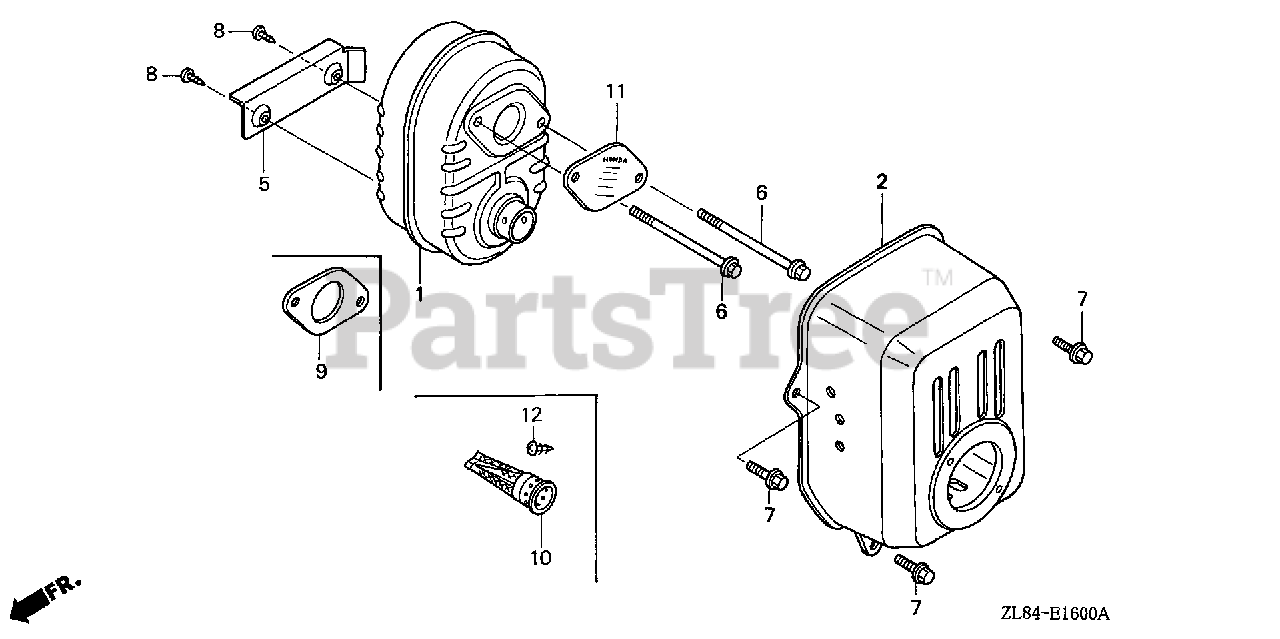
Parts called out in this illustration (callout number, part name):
1	MUFFLER
2	PROTECTOR, MUFFLER
5	SHROUD, MUFFLER
6	BOLT, FLANGE (6X79) (CT200)
7	BOLT, FLANGE (6X12) (CT200)
8	SCREW, TAPPING (4X6)
9	GASKET, MUFFLER
